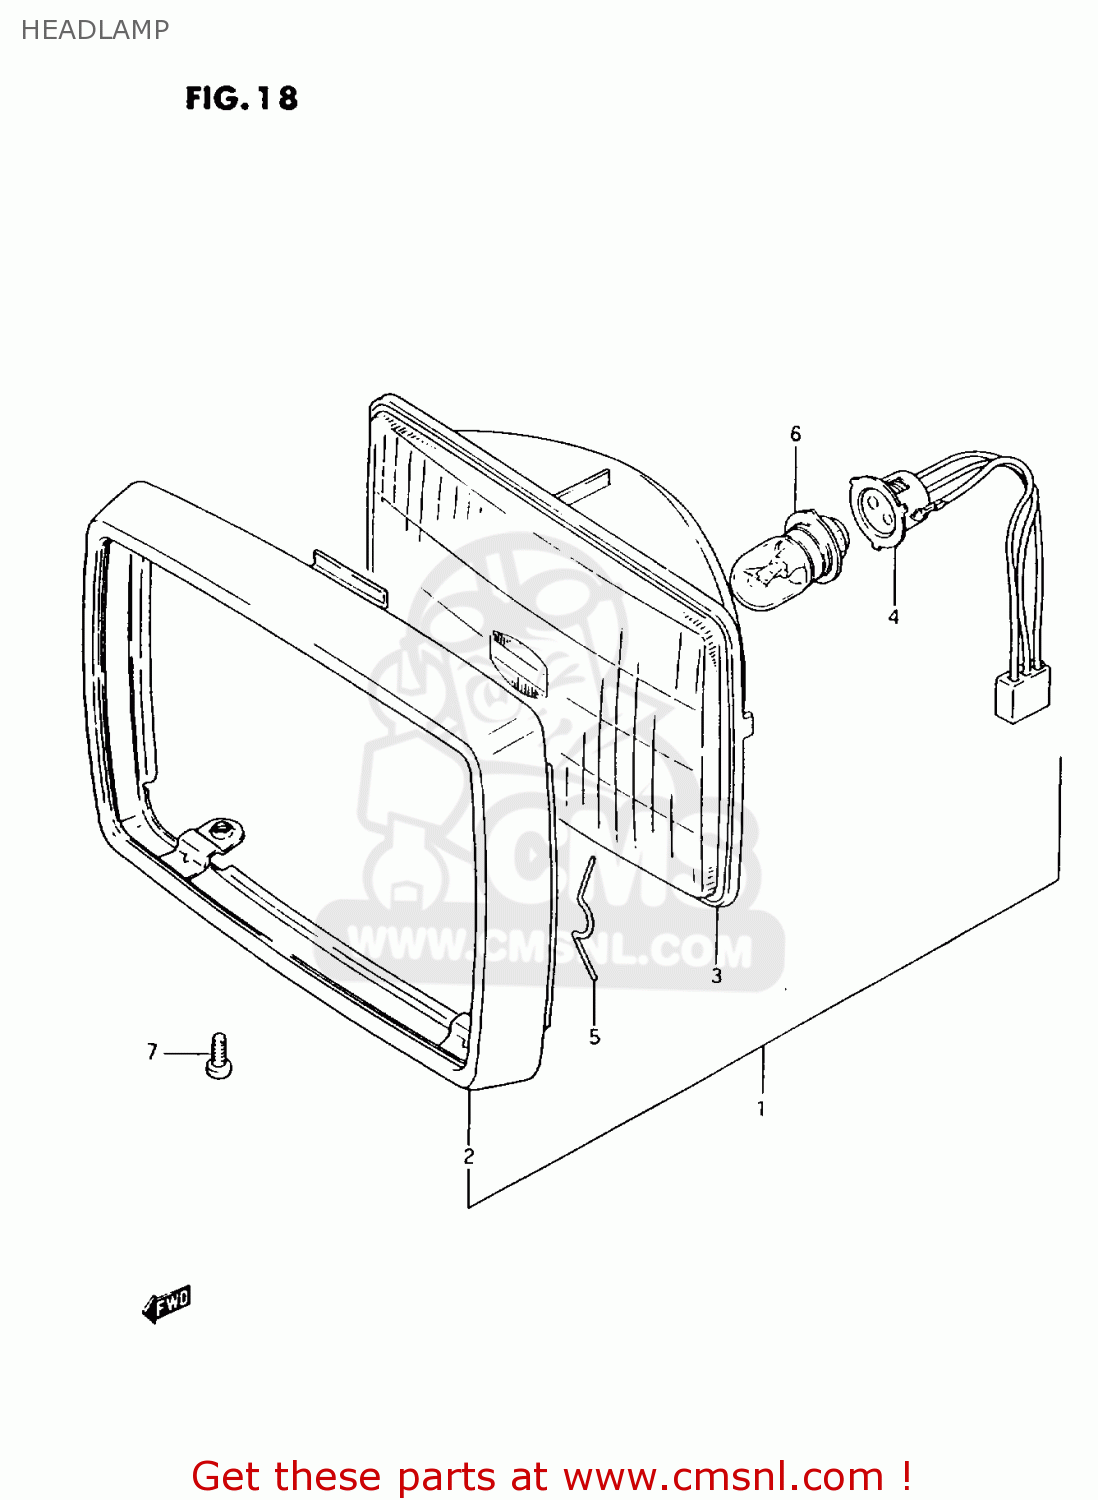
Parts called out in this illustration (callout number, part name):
1	HEADLAMP ASSY
2	RIM,HEAD LAMP
3	LAMP UNIT
4	SOCKET
5	SPRING
6	BULB(6V,25/25W,A3627)
7	SCREW
